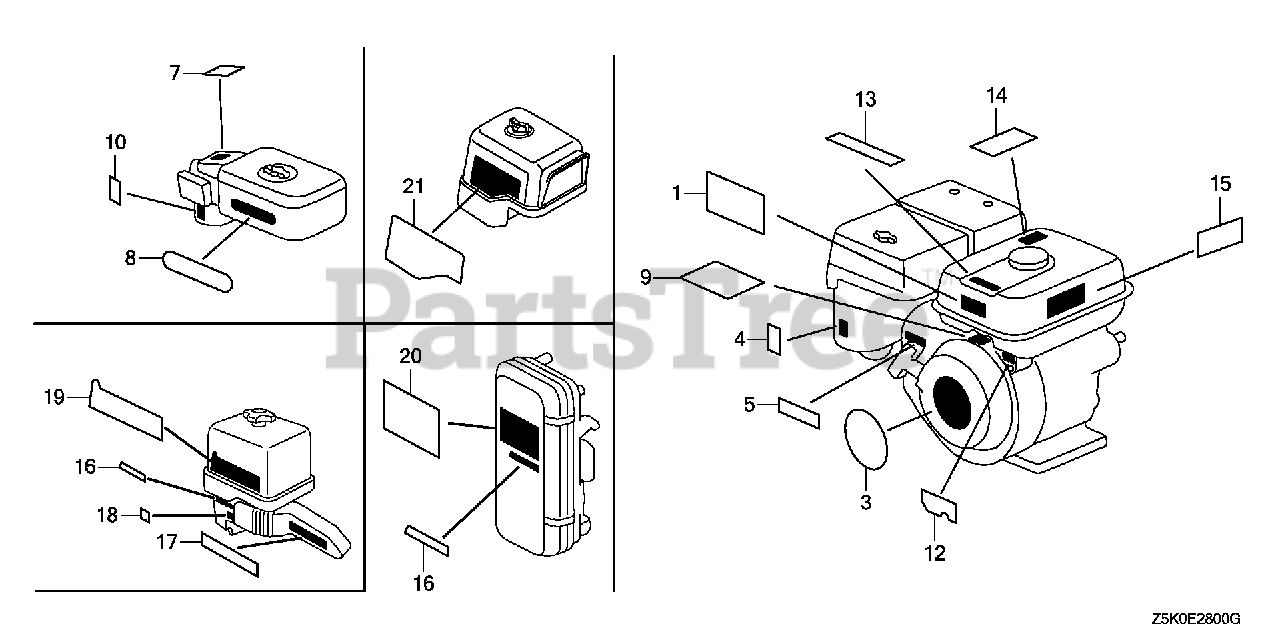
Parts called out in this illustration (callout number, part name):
1	MARK, OPERATOR CAUTION (ENGLISH)(MADE IN THAI)
1	MARK, OPERATOR CAUTION (PICTOGRAPH)(MADE IN THAI)
1	MARK, OPERATOR CAUTION (PICTOGRAPH)
3	EMBLEM (GX270 9.0)
3	EMBLEM (GX270)
4	MARK, CHOKE (GRAY)
5	MARK, THROTTLE INDICATION
